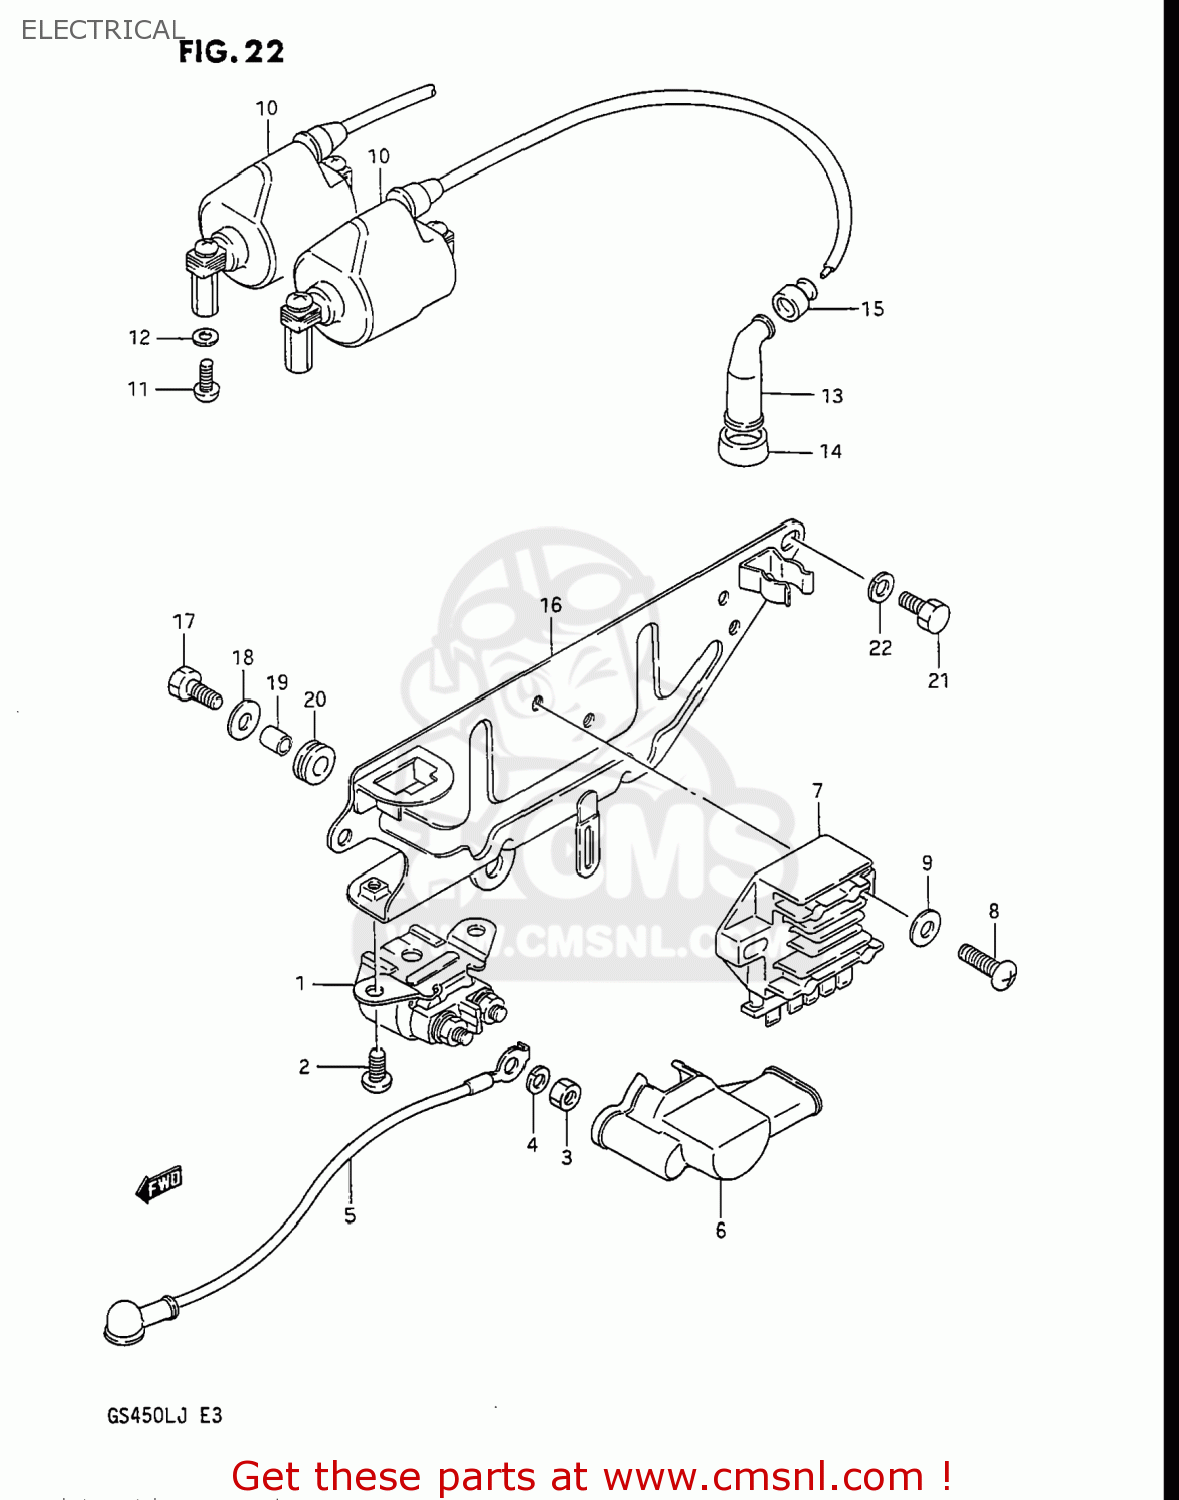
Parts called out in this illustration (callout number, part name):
1	RELAY ASSY,STARTING MOTOR
2	SCREW
3	NUT
4	WASHER,LOCK
5	WIRE,STARTER MOTOR LEAD
6	CAP,STARTER RELAY
7	RECTIFIER ASSEMBLY
8	SCREW
9	WASHER
10	COIL ASSEMBLY,IGNITION
11	SCREW
12	LOCK WASHER
13	CAP,SPARK PLUG
14	SEAL,SPARK PLUG
15	SEAL,SPARK PLU
16	HOLDER,ELECTRONIC PARTS
17	BOLT,M6X1X20
18	WASHER
19	SPACER (6.1X8X9.5)
20	CUSHION
21	BOLT
22	WASHER,LOCK
